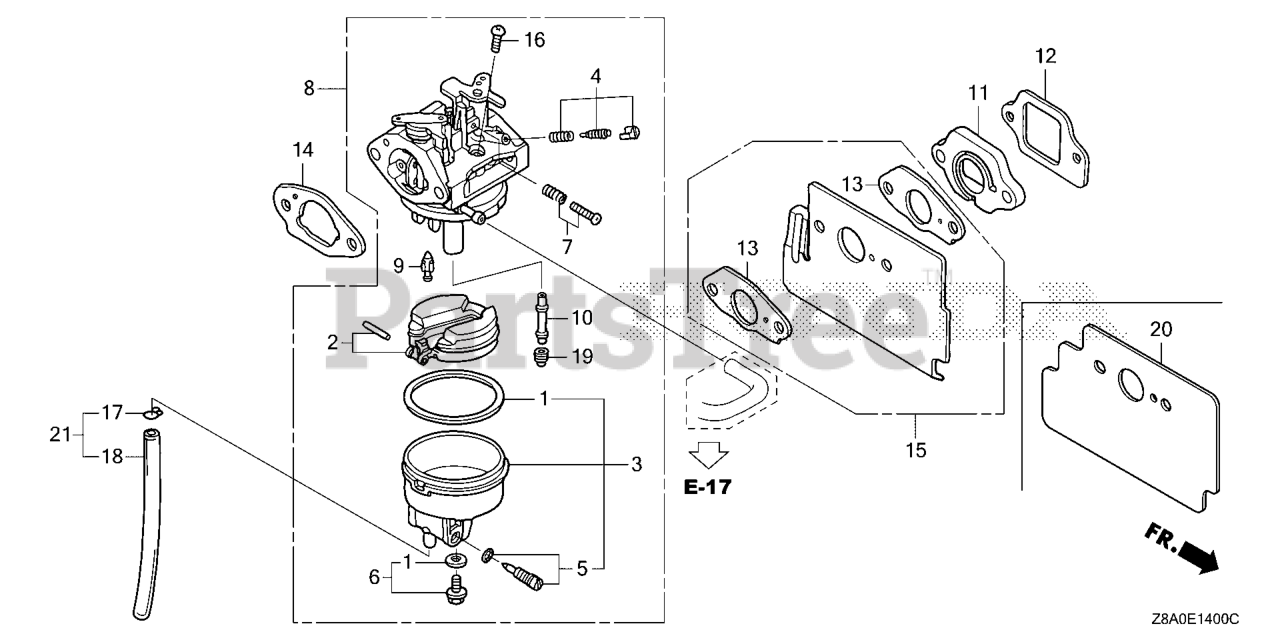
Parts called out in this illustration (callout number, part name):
1	GASKET SET
2	FLOAT SET
3	CHAMBER SET, FLOAT
4	SCREW SET (CARBURETOR NO.)
5	SCREW SET, DRAIN (ADVENTURE GREEN) (CARBURETOR NO.)
6	SCREW SET B
6	SCREW SET
7	SCREW SET (THROTTLE STOP) (CARBURETOR NO.)
8	CARBURETOR ASSY. (BB61J B)
8	CARBURETOR ASSY. (BB65P A)
8	CARBURETOR ASSY
9	VALVE, FLOAT (CARBURETOR NO.)
10	NOZZLE, MAIN (CARBURETOR NO.)
10	NOZZLE, MAIN
11	INSULATOR, CARBURETOR
12	GASKET, INSULATOR
13	GASKET, CARBURETOR
14	GASKET, CARBURETOR (Honda Code 5580253). (CHOKE SIDE)
15	GUIDE, AIR
16	SCREW, PAN (5X6)
17	CLIP, TUBE (B6.5)
18	BULK HOSE, VINYL (4X7X8000) (95003-07(95003-07001-60M) (CARBURETOR NO.)
19	JET, MAIN (#60) (Honda Code 0635474). (CARBURETOR NO.)
19	JET, MAIN (#62) (Honda Code 0635482). (CARBURETOR NO.)
19	JET, MAIN (#65) Use up to Engine SN BB30A D.
20	GUIDE, AIR
21	TUBE ASSY., DRAIN
